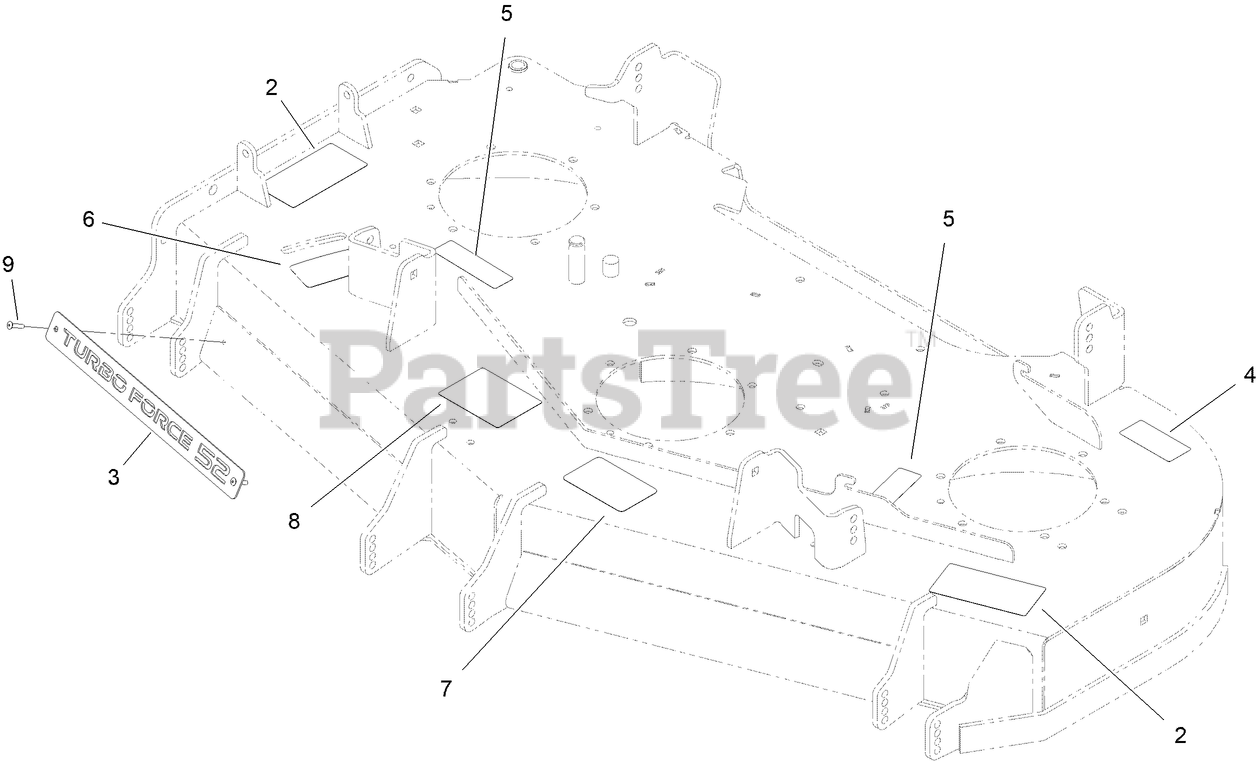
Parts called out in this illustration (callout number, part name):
2	DECAL-DANGER
3	PLATE-TURBO FORCE [BLACK]
4	DECAL-BOLT TORQUE
5	DECAL-COVER, MISSING
6	DECAL - BAFFLE ADJUSTMENT
7	DECAL-BELT, TENSION
8	DECAL-SCALP, ANTI
9	RIVET-TRIFOLD
